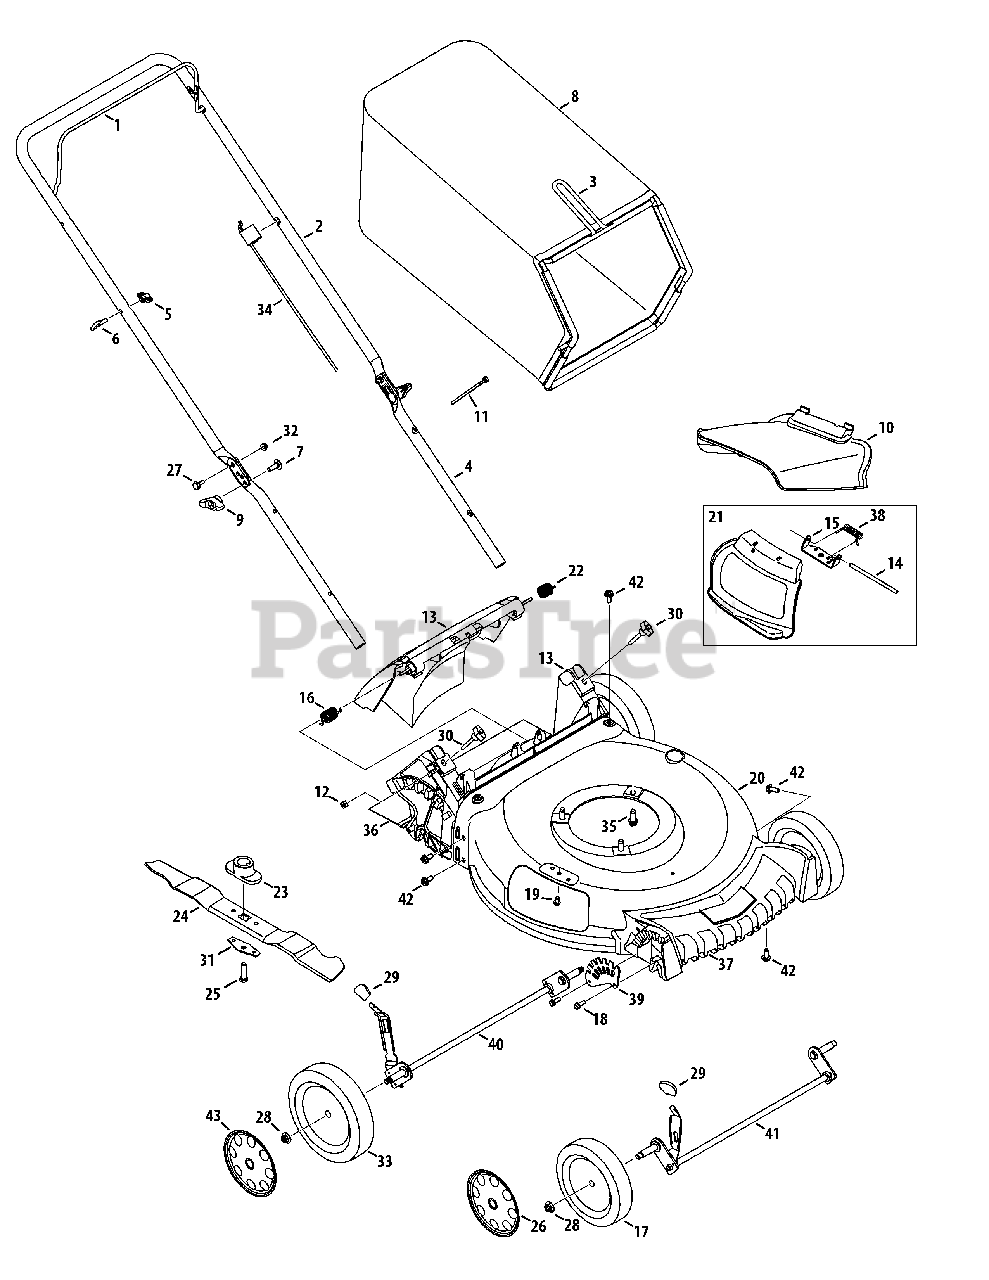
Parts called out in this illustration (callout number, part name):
1	Blade Control
2	Upper Handle
3	Grass Catcher Frame
4	Lower Handle
6	Rope Guide
7	Carriage Screw ,5/16-18
8	Grass Bag
10	Side Chute
11	Cable Tie
12	Nut, Sq., 1/4-20
13	Rear Discharge Door Assembly
13	Rear Discharge Door Assembly-(Lowes)
15	Chute Deflector Bracket
16	Torsion Spring - RH
17	Front Wheel
18	Screw, 1/4-15 x .750
19	Screw, 1/4-20 x .500
21	Hinged Mulch Plug Assembly
22	Torsion Spring - LH
23	Blade Adapter
24	Mulching Blade
25	Screw , 3/8-24 x 1.50
26	Hub Cap, 7"
27	Sldr. Screw, .375 x .126 x 1/4-20
28	Flange Lock Nut, 3/8-16
29	Adjustment Lever Knob
31	Blade Bell Support
32	Nut, Flange Lock, 1/4-20
33	Rear Wheel
34	Control Cable
35	TT Sems Screw, 3/8-16 x 1.0
36	Trail Shield
37	Front Cover
38	Torsion Spring
39	Front Height Adjuster Plate
40	Rear Axle Assembly
41	Front Axle Assembly
42	Screw, 5/16-14 x .750
43	Hub Cap, 8"
